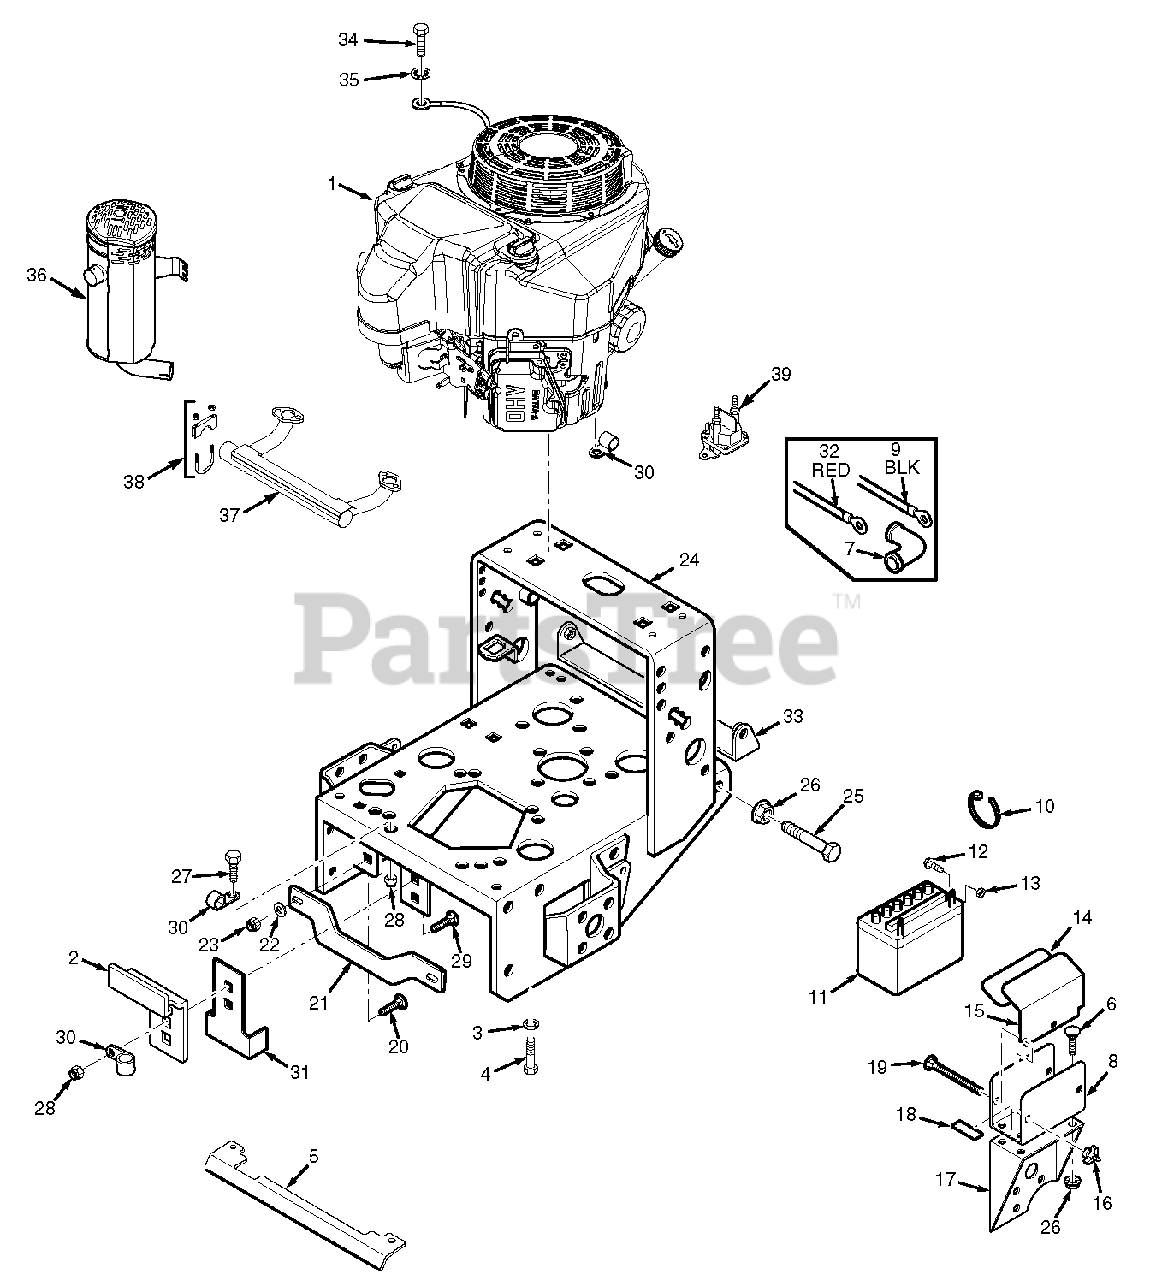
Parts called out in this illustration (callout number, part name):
1	Engine, Kawasaki FS22 (FS651V)
2	Plate, Clutch Bracket
3	Lock Washer 3/8"
4	Bolt, Hex Head 3/8-16 x 1-1/4"
5	Heatshield, 20" Large Frame
6	Carriage Bolt, 5/16-18 x .75"
7	Rubber Boot
8	Battery Box
9	Battery Cable, 31.5" Black
10	Cable Tie
11	Battery (Not Available Through Scag)
12	Bolt, 1/4-20 x 1/2"
13	Nut, 1/4-20
15	Battery Cover
16	Wing Nut, 1/4-20
17	Battery Support
18	Pad, Rubber
19	Bolt, 1/4-20 x 6" Carriage
20	Carriage Bolt, 3/8-16 X 1-1/4"
21	Brace, 20" Large Frame
22	Flat Washer .391 x .938 x .105
23	Nut, 3/8-16 Elastic Stop
24	Engine Deck, 20" Wide, w/decals
25	Bolt, 5/16-18 x 2" Hex Head
26	Nut, 5/16-18 Serr. Flange
27	Hex Head Bolt, 5/16-18 x .75"
28	Nut, 5/16-18 Elastic Stop
29	Carriage Bolt, 5/16-18 x 1"
31	Clutch Bracket
32	Battery Cable, 25" Red
32	Battery Cable, 18" Red
33	Pulley Guard, 20" Frame
34	Bolt, Hex Head M8-1.25 x 16
35	Lockwasher, 5/16" Ext. Tooth
36	Muffler
37	Exhaust Manifold
38	Clamp, Muffler 1-1/4" Dia.
39	Solenoid
